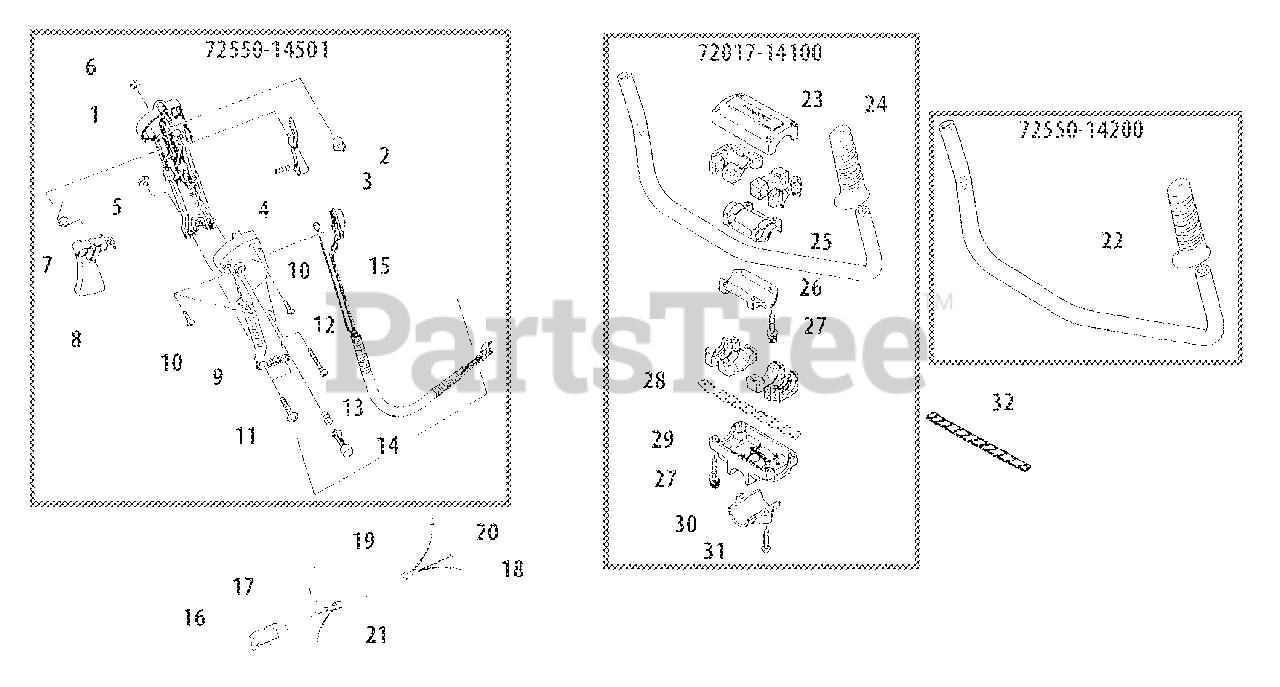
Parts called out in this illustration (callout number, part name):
1	HANDLE, CONTROL - RIGHT
2	PLUG
3	LEVER, TRIGGER LOCKOUT
4	SPRING
5	NUT - 5
6	NUT - 4
7	SPRING
8	TRIGGER, THROTTLE
9	HANDLE, CONTROL - LEFT
10	SCREW - 4X16 -- TAPPING
11	SCREW - 5X20
12	SCREW - 4X23
13	SPRING
14	BUTTON, THROTTLE LOCK
15	CABLE, THROTTLE - A
16	CONNECTOR TUBE
17	SLEEVE
18	CABLE, THROTTLE - B
19	TUBE
20	WIRE
21	WIRE
22	GRIP
23	CAP - UPPER
24	CUSHION - UPPER
25	CLAMP - UPPER
26	CLAMP - LOWER
27	SCREW - 5X25
28	CUSHION - LOWER
29	BRACKET, HANDLE
30	SPACER
31	SCREW - 6X25
32	LEAD - GROUND
72017-14100	HANDLE BRACKET KIT
72550-14200	HANDLE ASSY
72550-14501	THROTTLE LEVER ASSY
